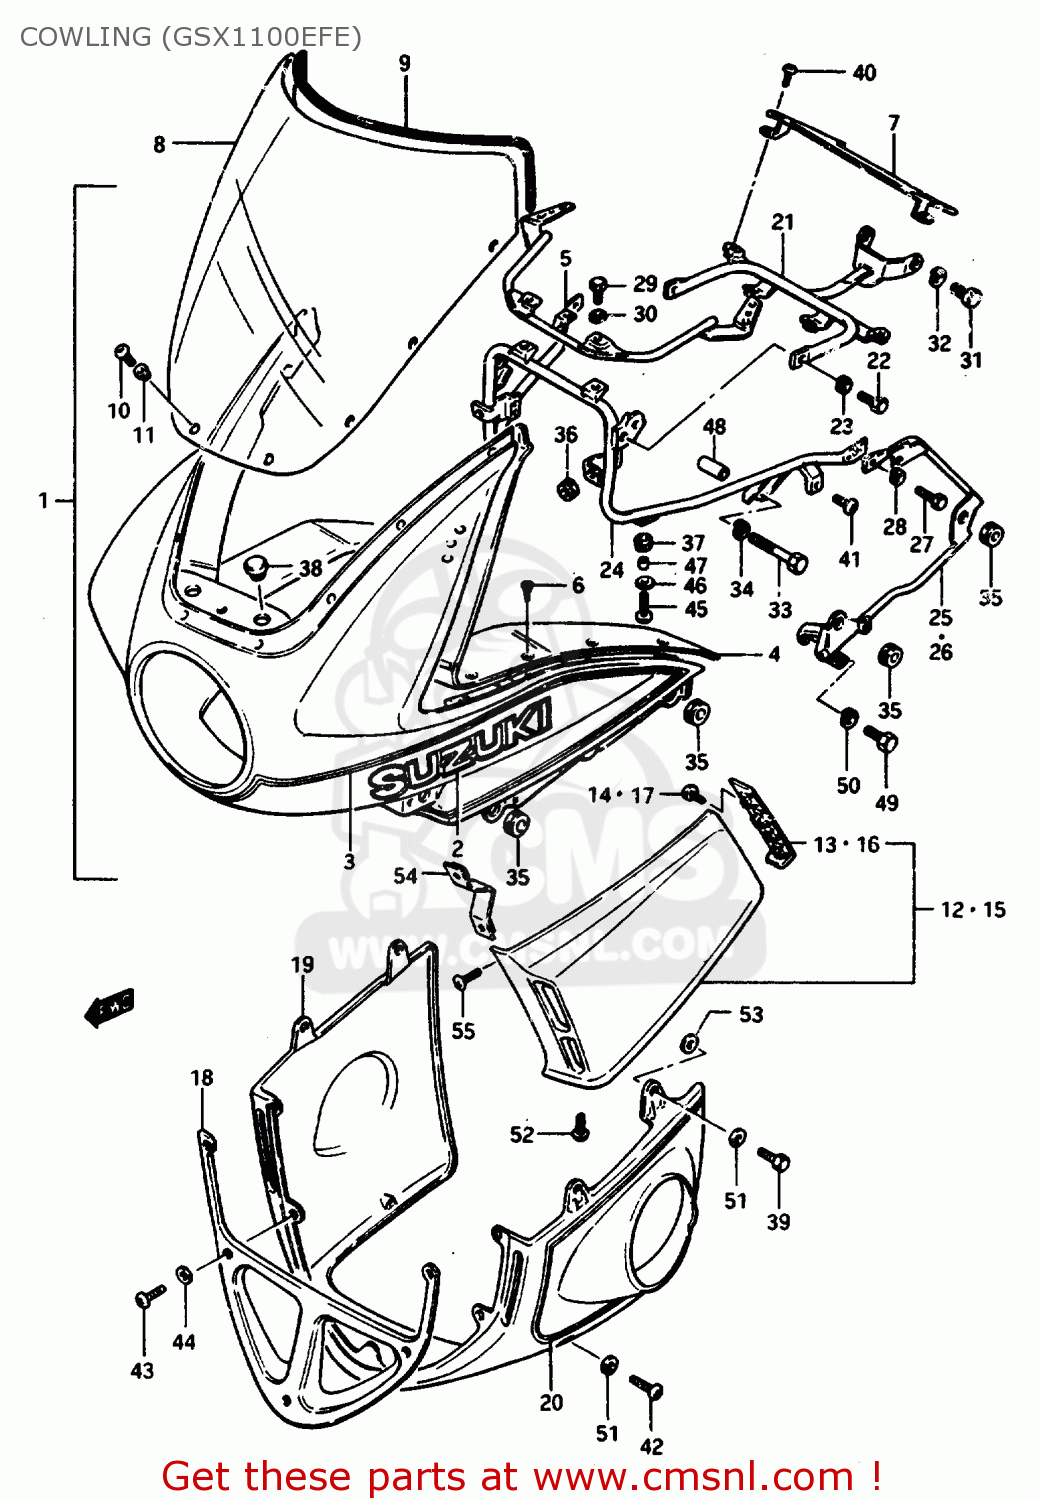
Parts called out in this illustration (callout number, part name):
1	COWLING ASSY
2	EMBLEM
3	TAPE SET
4	PANEL,COWLING
5	BRACE,COWLING BODY
6	SCREW, PANEL
7	COVER,METER,REAR
8	SCREEN
9	MOLDING
10	SCREW(5X20)
11	CUSHION
12	COVER,COWLING
13	PANEL,COWL SIDE COVER RR RH
14	SCREW
15	COVER, LH (WHITE)
16	PANEL,COWLING SIDE COVER
17	SCREW
18	COVER,LOWER,CENTER
19	COVER (WHITE/RED)
20	TAPE SET
21	BRACE,COWLING,FRONT
22	BOLT
23	LOCK WASHER
24	BRACE,COWL RR
25	BRACE,COWLING SIDE,RIGHT
26	BRACE,COWLING SIDE,LEFT
27	BOLT 6X16
28	LOCK WASHER
29	BOLT
30	LOCK WASHER
31	BOLT
32	LOCK WASHER
33	BOLT
34	LOCK WASHER
35	CUSHION
36	CUSHION
37	CUSHION
38	PLUG(OD:22)
39	SCREW, CENTER
40	SCREW
41	SCREW 6X12
42	SCREW, CENTER
43	SCREW
44	WASHER
45	SCREW, CENTER
46	WASHER(6.5X18X1)
47	SPACER (6.1X9X9)
48	SPACER (8.6X13.8X35)
49	BOLT
50	LOCK WASHER
51	WASHER
52	SCREW
53	WASHER(6X13X2)
54	BRACE,SIDE,FRONT
55	SCREW
